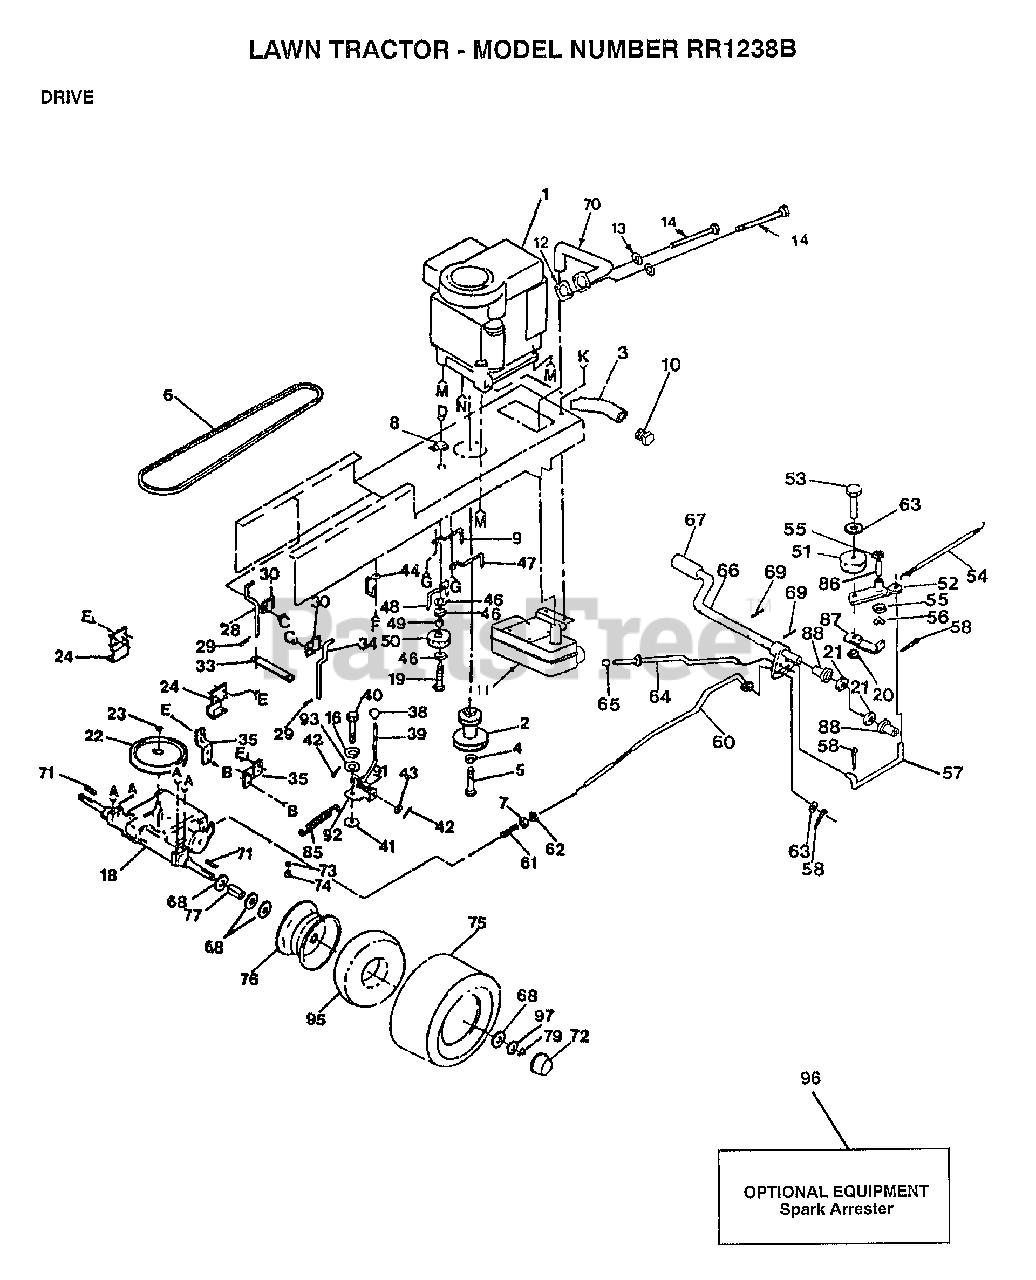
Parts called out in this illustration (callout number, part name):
1	ENGINE BRIGGS AND STRATTON
4	LOCKWASHER
5	BOLT
6	BELT-V.90.0.GD.DR
7	NUT
8	CLIP T
9	KEEPER BELT ENGLH
11	MUFFLER EUROPE
13	LOCKWASHER
14	SCREW LT
16	LOCKWASHER
19	BOLT
21	WASHER LT
22	PULLEY TRANS
24	BRACKET LT
28	KEEPER BELT LH
29	SPRING.RETAINER
30	CLAMP LT
33	STRAP LOCATOR
34	KEEPER BELTRH
35	STRAP TORQUE
39	ROD SHIFTER
41	WASH-SHFT PLT LT
42	PIN COTTER 1/8
43	WASHER
46	WASHER
47	"KEEPER,BLT ENG LT"
48	BELT KEEPER LT
49	SPACER T
50	PULLEY.IDLER.FLAT
52	ARM IDLER
54	"SPRING, RETURN LT"
55	WASHER LT
56	KLIP RING
57	"LINK, CLUTCH T"
58	COTTER PIN
60	BRAKE ROD LT
61	SPRING ROD LT
62	NUT
63	WASHER
65	PLUNGER CAP T
67	PEDAL COVER T
68	WASHER
70	PIPE EXHAUST
71	SQUARE KEY
72	HUB CAP
73	VALVE CAP
74	VALVE STEM LT
77	SPACER LT
79	E-RING LT
86	"LY, BEARING"
87	RETAIN BELT
88	NYLON BEARING
91	SPRING LT
92	PLATE SHIFT LT
93	WASHER LT
95	TUBE.18X9.5-8
96	SPARK ARREST KIT
97	WASHER
